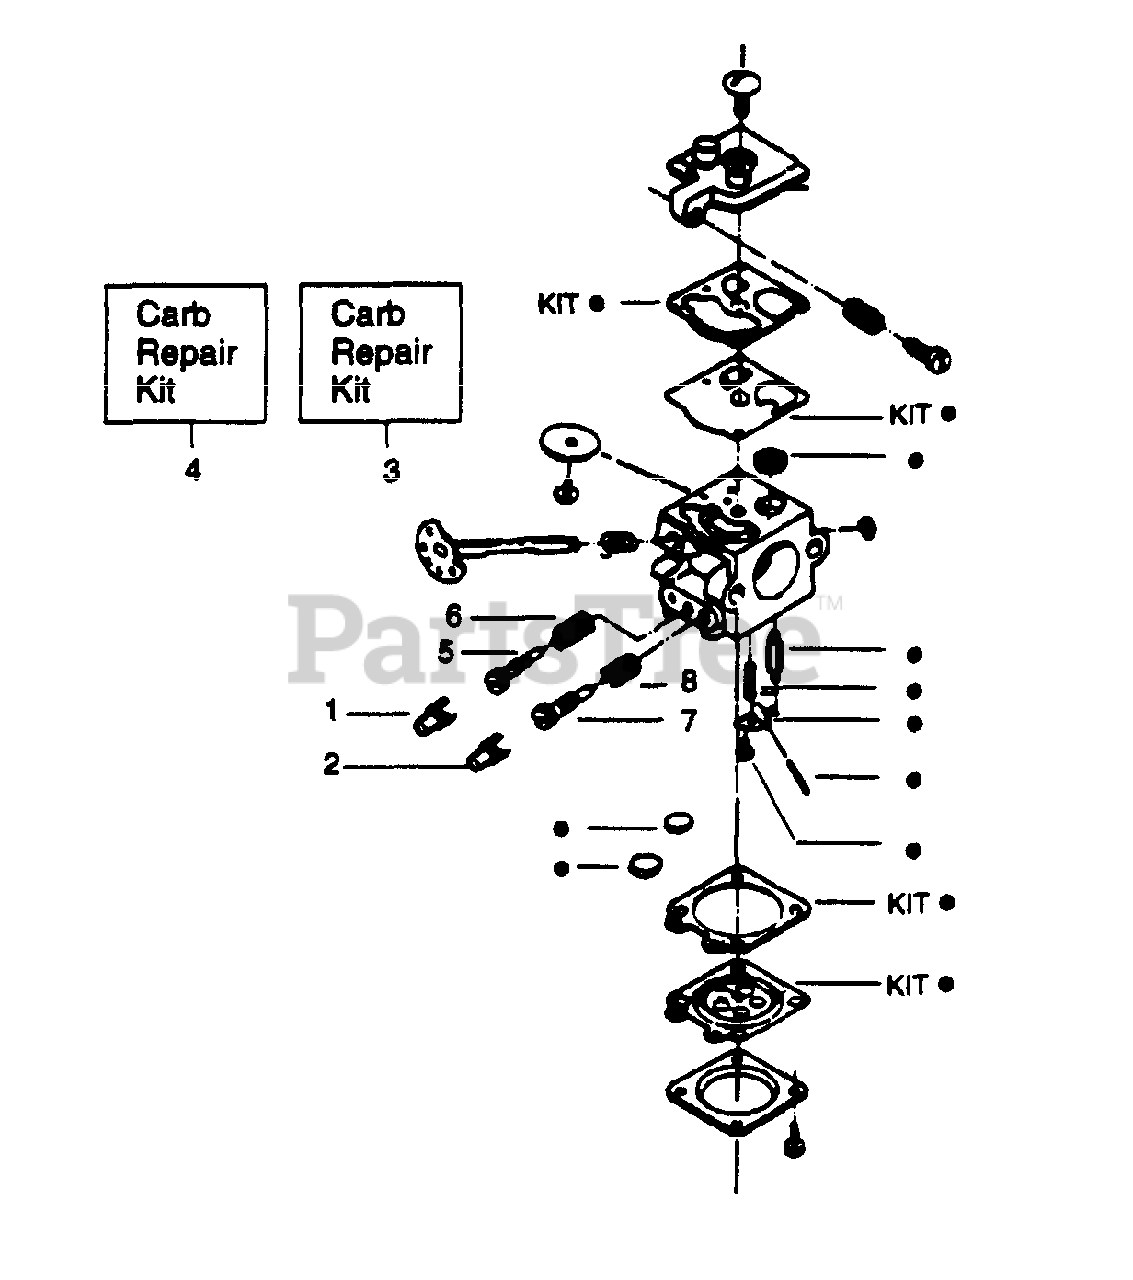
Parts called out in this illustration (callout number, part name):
1	Limiter Cap - High
2	Limiter Cap - Low
3	Carburetor Repair Kit
4	Gasket Diaphragm Kit
5	Low Speed Needle
6	Needle Spring Low Speed
7	High Speed Needle
8	Needle Spring High Speed
